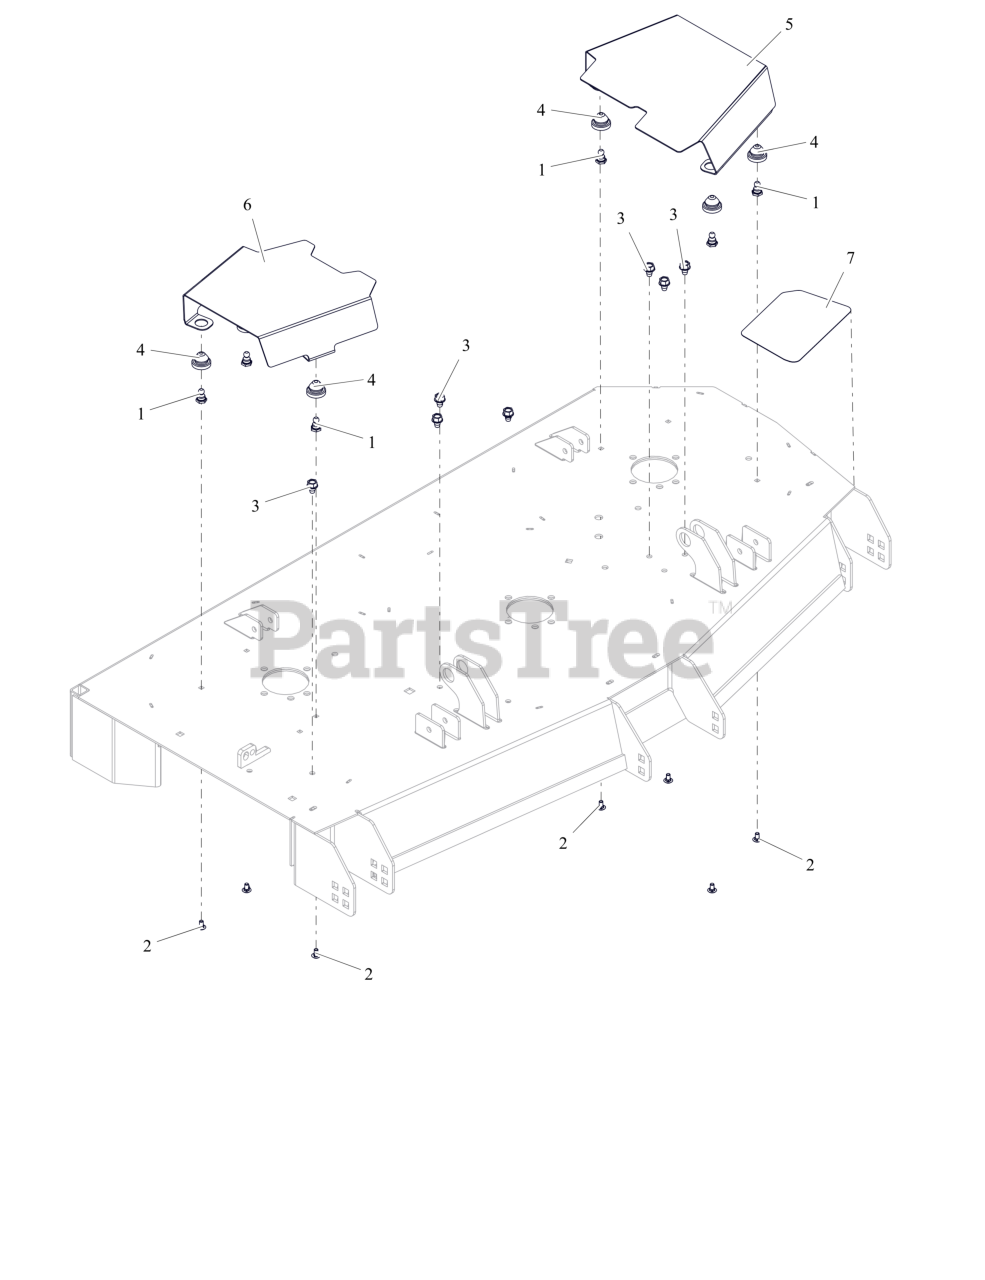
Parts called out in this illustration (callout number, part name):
1	STUD, BALL FEMALE .250-20 THREAD
2	BLT, RHSSN.25-20X.500 G5 ZCC
3	SCR,TAP .375-16X.50 HWH TR ZCC
4	COUPLING, RUBBER PUSH-IN
5	COVER- BELT 52" LEFT
6	COVER- BELT 52" RIGHT
7	GRIP, STEP ANTI SKID HD XF3
